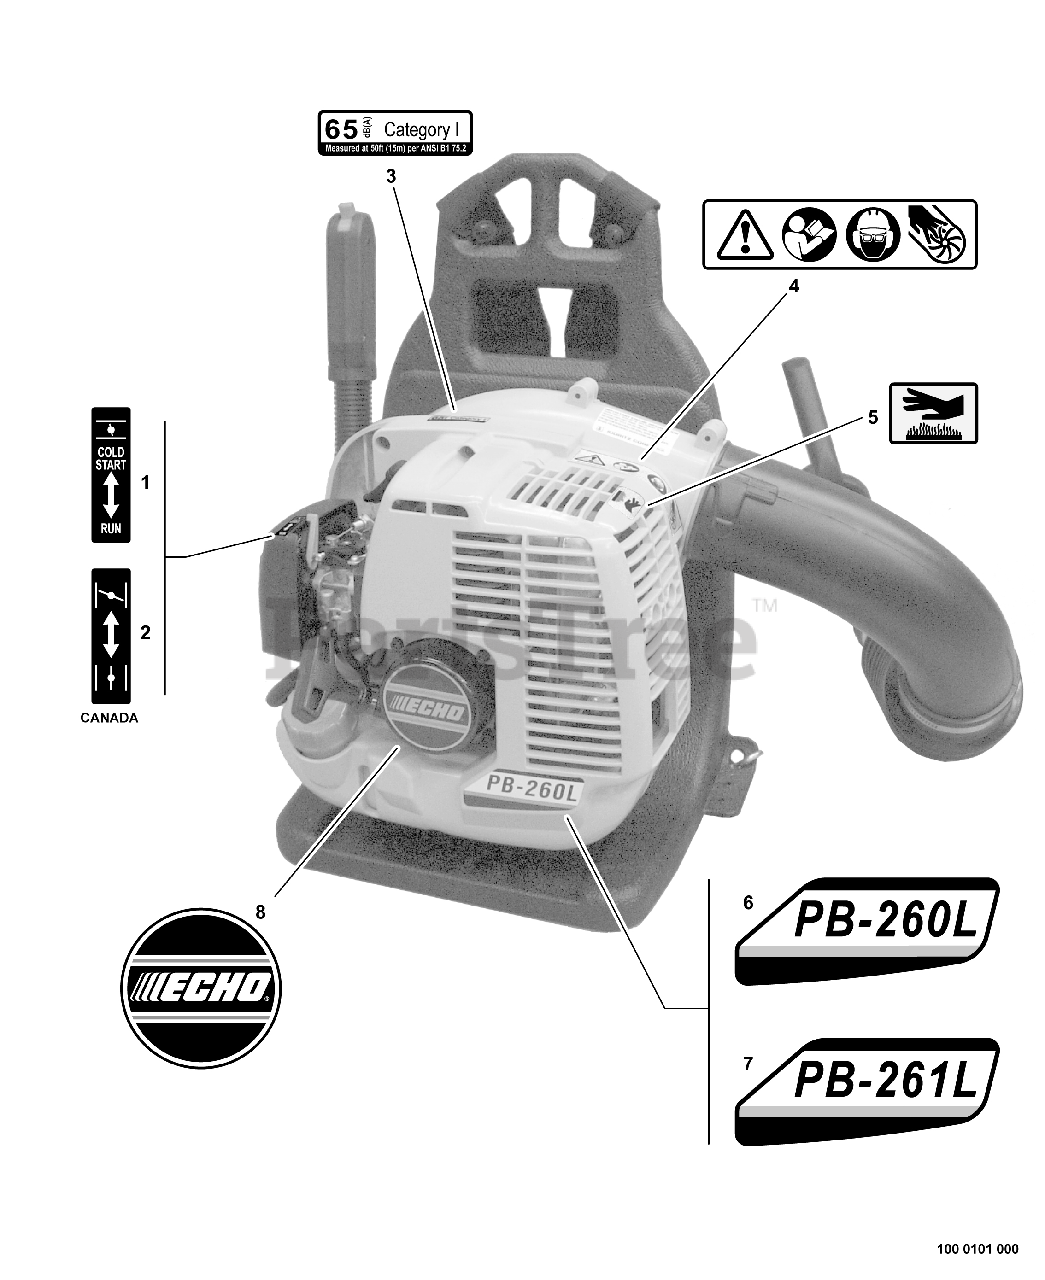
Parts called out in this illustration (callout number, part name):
1	LABEL - CHOKE
2	LABEL - CHOKE
3	LABEL - NOISE 65dB(A) CAT I
4	LABEL - CAUTION
5	LABEL - HOT SURFACE
6	LABEL - MODEL PB-260L
7	LABEL - MODEL PB-260L
8	LABEL - ECHO
